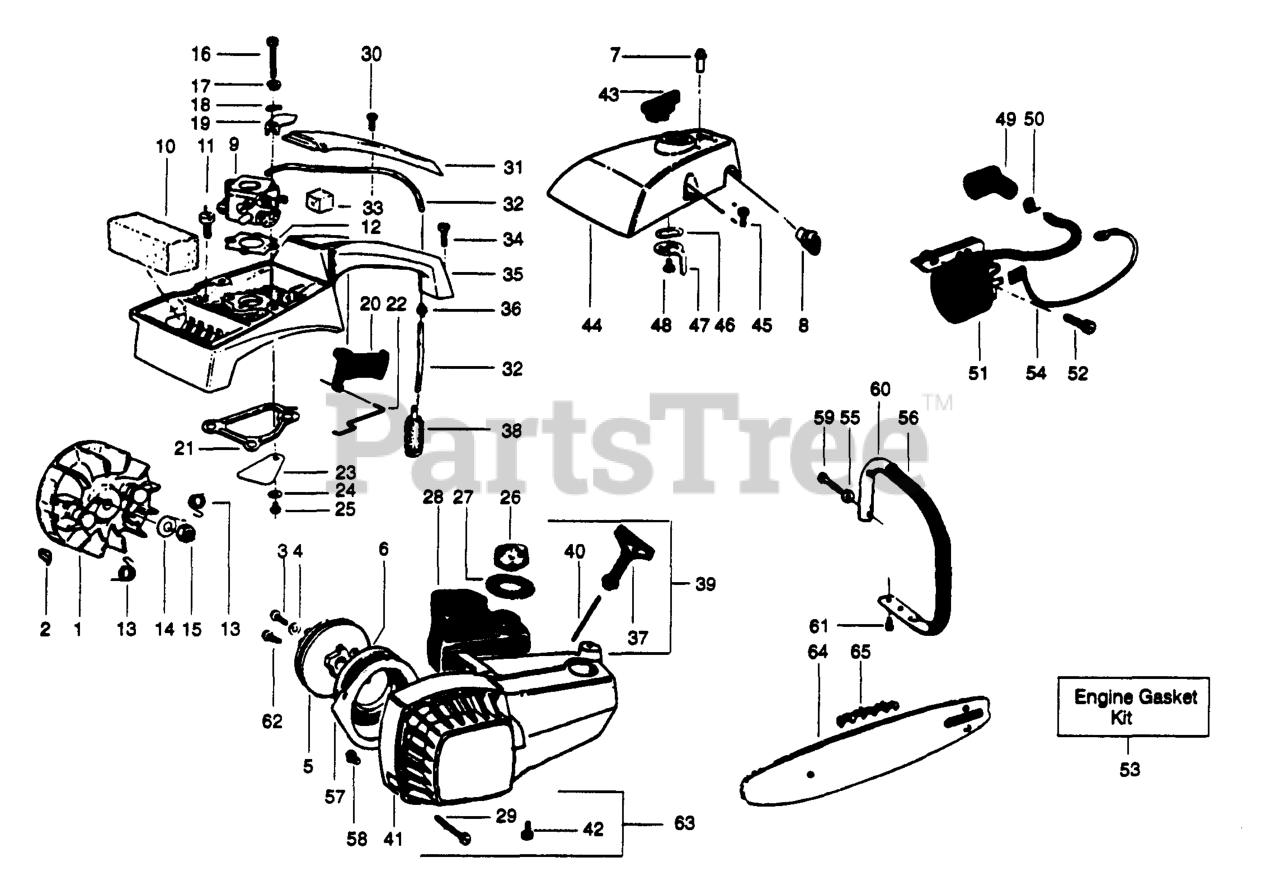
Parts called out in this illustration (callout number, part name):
1	FLYWHEEL ASSEMBLY
2	KEY-FLYWHEEL
3	SCREW
5	KIT-STARTER PULLEY
6	SPRING-STARTER
7	GROMMET, IDLE
8	GROMMET, MIXTURE
9	CARBURETOR W/ LIMITER CAPS
10	AIR FILTER
12	CARBURETOR GASKET
13	SPRING STR DOG
14	WASHER-FLYWHEEL
19	CHOKE SHUTTER
20	THROTTLE TRIGGER
21	GASKET
22	THROTTLE WIRE
23	REED VALVE
25	SCREW
26	CAP ASSY W/ RETAINER
28	Fuel Tank Ass'y.
29	SCREW
31	HANDLE COVER
32	KIT.LINE TANK/PURGE
34	SCREW-1/4-20 X 13/16
35	HANDLE & CARB HOUSING
36	FUEL LINE FITTING
37	HANDLE-STARTER
38	FUEL PICK UP ASSY
39	ASS'Y ROPE & HANDLE
41	FAN HOUSING KIT
42	SCREW-PINCH CLAMP-TYPE 2
43	CHOKE KNOB
44	CARB COVER
45	SCREW-10-24 X 5/8 FILL
46	WAVE WASHER
47	CHOKE LEVER
48	SCREW-8-16 (PLASTITE)
49	SPARK PLUG BOOT
50	CONNECTOR
51	IGNITION MODULE
52	SCREW 8-32 X 3/4
53	GASKET KIT
54	SWITCH LEAD
56	Grip-Handlebar
63	Fan Hsg. Screw Kit
64	Guide Bar
65	CHAIN
